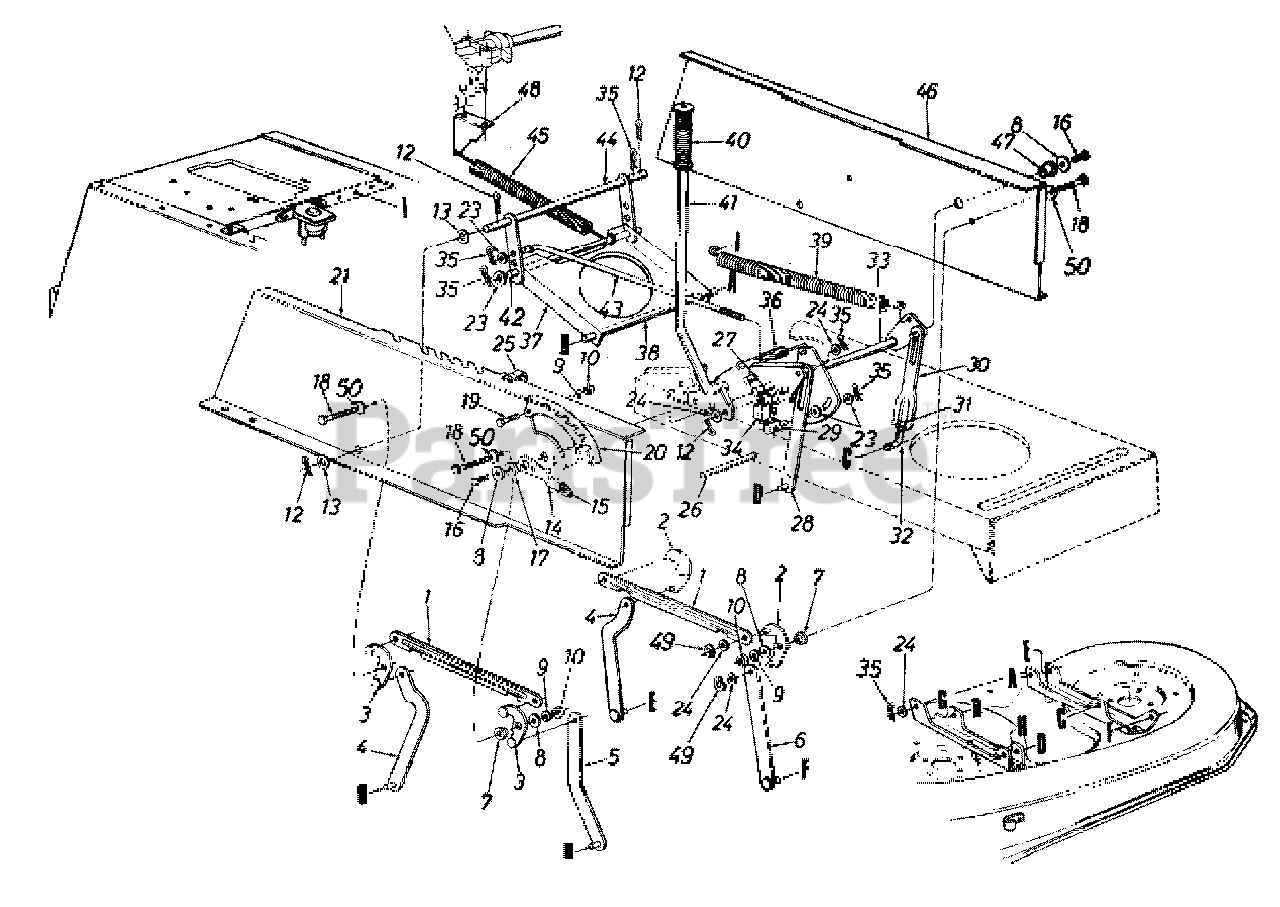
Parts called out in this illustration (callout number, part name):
3	Pivot Link Ass'y.-R.H.
7	Shld. Spacer .318" I.D.
8	Fl-Wash. .344" I.D. x .62" O.D.
9	L-Wash. 5/16" I.D.
10	Hex Nut 5/16-18 Thd. (Gr. 5)
12	Cotter Pin 1/8" Dia.
13	Fl-Wash. .635" I.D. x 1.0" O.D.
14	Height Adj. Stop Lever Ass'y.
15	Knob
16	Hex Wash. TT-Tap Scr. 5/16-18 x
17	Flange Brg. .63" I.D.
18	Hex Wash. Hd. Scr. 5/16-18 x .875" Lg.
19	Hex Bolt 5/16-18 x .75" Lg.
20	Index Brkt.
24	Fl-Wash. .531" I.D. x .93" O.D.
26	Running Board Rod
27	Hex Wash. Hd. Tap Scr.
31	Hex Nut 1/2-20 Thd. (Gr. 5)
32	Lift Link Adjuster
35	Inter. Cotter Pin 3/8" Dia.
36	Extension Spring
39	Extension Spring
40	Grip (Lift Handle)
43	Disengagement Rod
49	"E"-Ring
50	Bell-Wash. .325" I.D.
97675A-0637	LIFT HANDLE ASSY POWDER BLACK - POWDER BLACK (0637)
97675A-0638	LIFT HANDLE ASSY POWDER BLACK - MTD/TROY-BILT RED (0638)
97675A-0648	LIFT HANDLE ASSY POWDER BLACK - TECH GRAY (0648)
97675A-0665	LIFT HANDLE ASSY POWDER BLACK - YARDMAN GREEN (0665)
